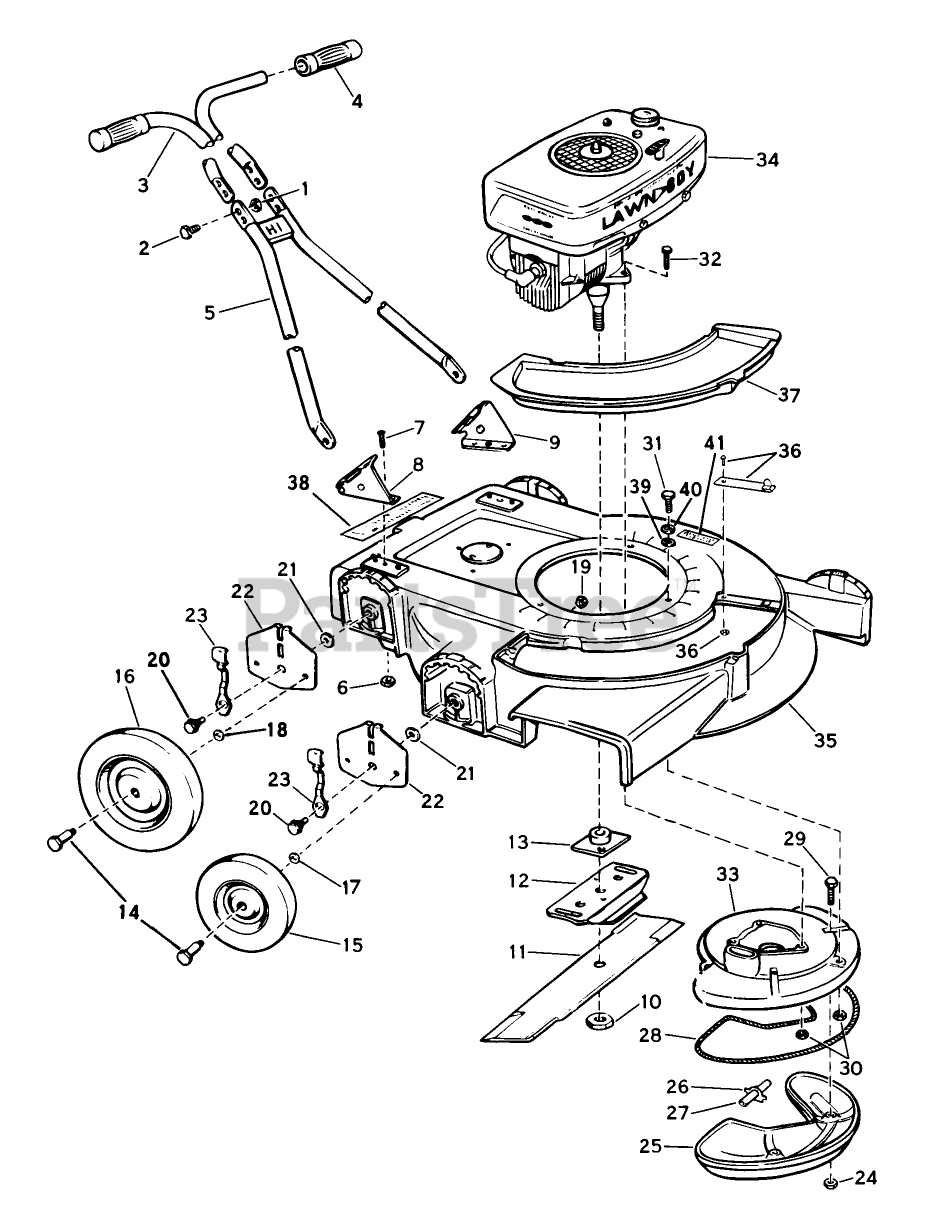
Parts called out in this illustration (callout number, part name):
1	STOP NUT
4	HANDLE GRIP
10	NUT-BLADE
13	PLATE AND COLLAR ASM
14	BOLT WHEEL
17	WASHER WROUGHT
18	WASHER WROUGHT
24	LOCKNUT E
26	Gasket-Internal Tube
27	Tube-Internal Muffler
35	Housing Cover Assy. 19"
36	Spring, Rivet Washer Assy.
38	Decal, Instruction
